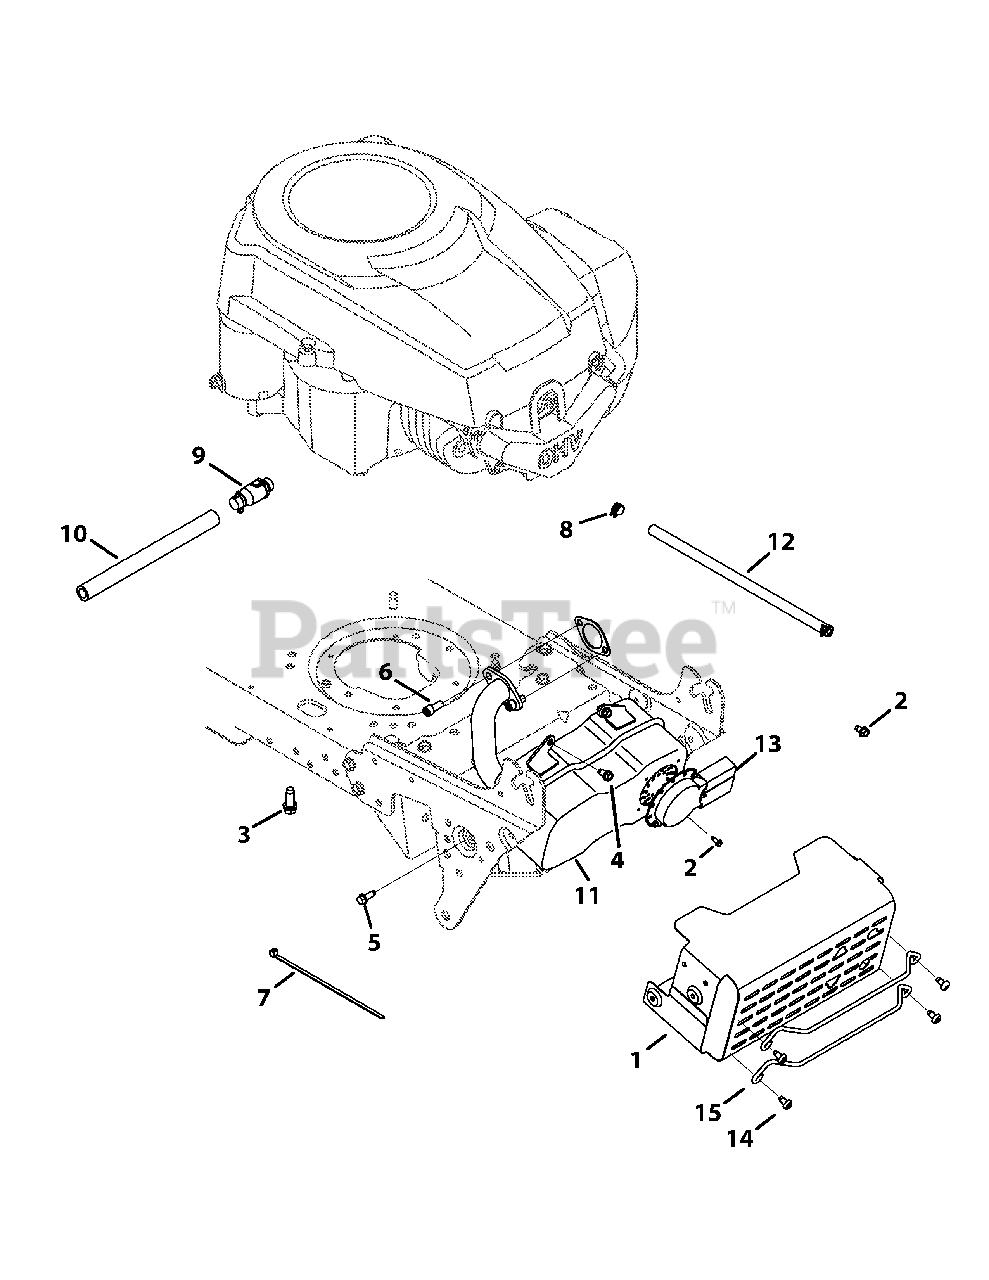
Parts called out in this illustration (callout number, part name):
1	Muffler Shield Assembly
2	Screw, 8-18 x .500
3	Screw, 3/8-16 x 1.0
4	Screw, 1/4-20 x .500
5	Screw, 1/4-20 x .750
6	Socket Screw, 5/16-18 x .750
7	Cable Tie
8	Clamp Hose, .490 diameter
10	Oil Drain, Extension Hose
11	Muffler
12	Fuel Hose, Low Permeation
13	Muffler Deflector Long
14	Pan Torx Screw 1/4
15	Muffler Guard Rod
